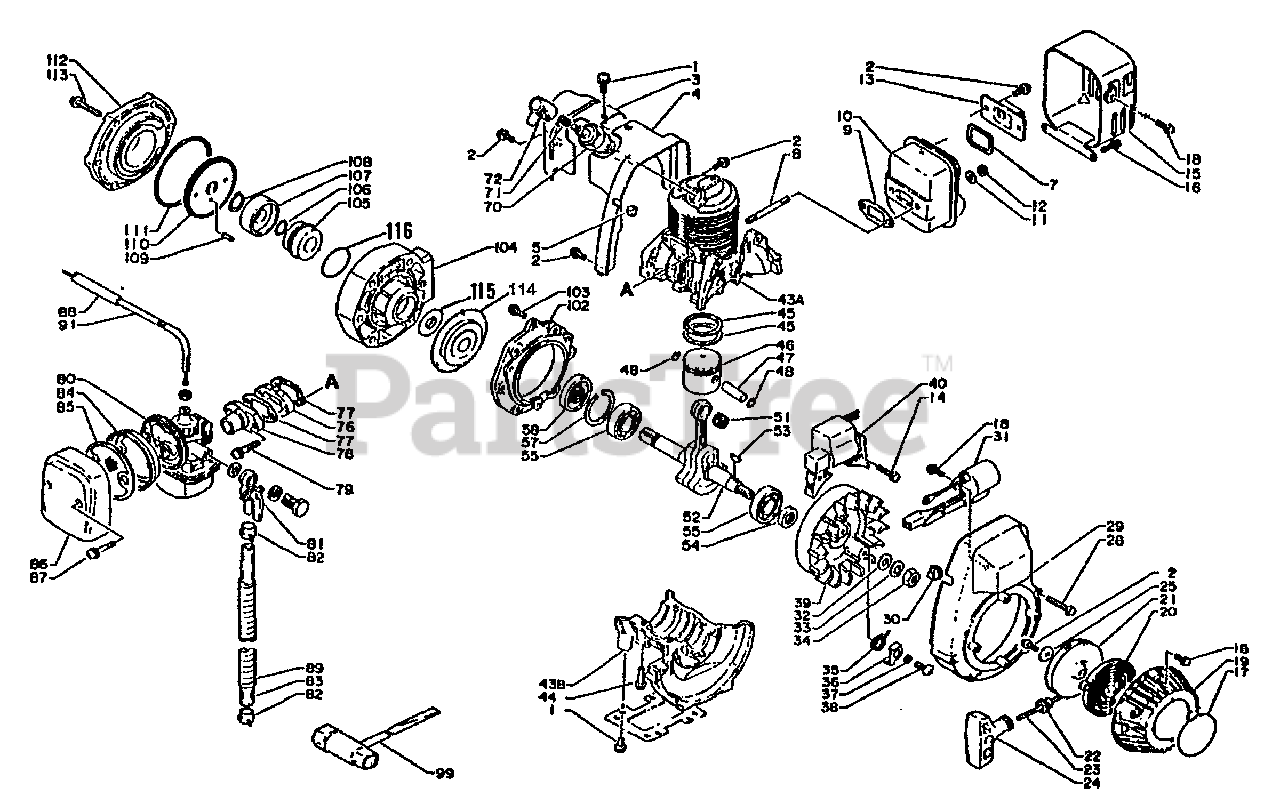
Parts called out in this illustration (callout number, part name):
1	SCREW - 5X10
2	SCREW - 4X10
3	PLATE, GUIDE
4	COVER, CYLINDER
7	GASKET, EXHAUST
9	GASKET, EXHAUST
11	WASHER - 5
12	LOCKNUT - 5
13	GUIDE, EXHAUST
14	SCREW - 4X20
15	COVER, MUFFLER
16	SCREW - 4X12
17	LABEL - ECHO
18	SCREW - 4X14
19	CASE, STARTER
20	SPRING, REWIND
21	REEL, ROPE
22	GUIDE, ROPE
23	ROPE, STARTER - 3X850
24	GRIP, STARTER
28	SCREW - 4X40
29	CASE, FAN
31	COIL, IGNITION
32	WASHER - 8
33	LOCKWASHER - 8
35	SPRING, RETURN
36	PAWL, STARTER
38	SCREW - 5X14
39	FLYWHEEL
40	COIL, IGNITION
43	CASE, CYLINDER SET
43A	CASE, CYLINDER SET
43B	CASE, CYLINDER SET
44	SCREW - 5X30
45	RING, PISTON
47	PIN, PISTON
48	RING, RETAINING
51	BEARING, NEEDLE
52	CRANKSHAFT ASSY
54	SEAL, OIL
55	BEARING, BALL - 6201
57	RING, RETAINING - 32
58	SEAL, OIL
70	SPARK PLUG -- BM-6A
71	TERMINAL, SPARK PLUG CAP
72	CAP, SPARK PLUG
76	INSULATOR, INTAKE
77	GASKET, INTAKE
78	ADAPTOR, INTAKE
79	SCREW - 5X25
80	CARBURETOR
81	FUEL VALVE ASSY
82	CLAMP
83	PIPE - FUEL
84	CASE, AIR FILTER
85	FILTER, AIR
86	COVER, AIR FILTER
87	SCREW - 4X28
88	TUBE
89	TUBE, SPIRAL
91	CABLE, THROTTLE
99	T-WRENCH - 10X19mm
102	BRACKET, PUMP
103	SCREW - 5X16
104	CASE, PUMP
106	O-RING
107	PLATE, DRIVE
108	RING, RETAINING - 12
110	IMPELLER
111	O-RING
112	LID, PUMP
113	SCREW - 5X40
115	PLATE, SEAL
116	O-RING - 29
